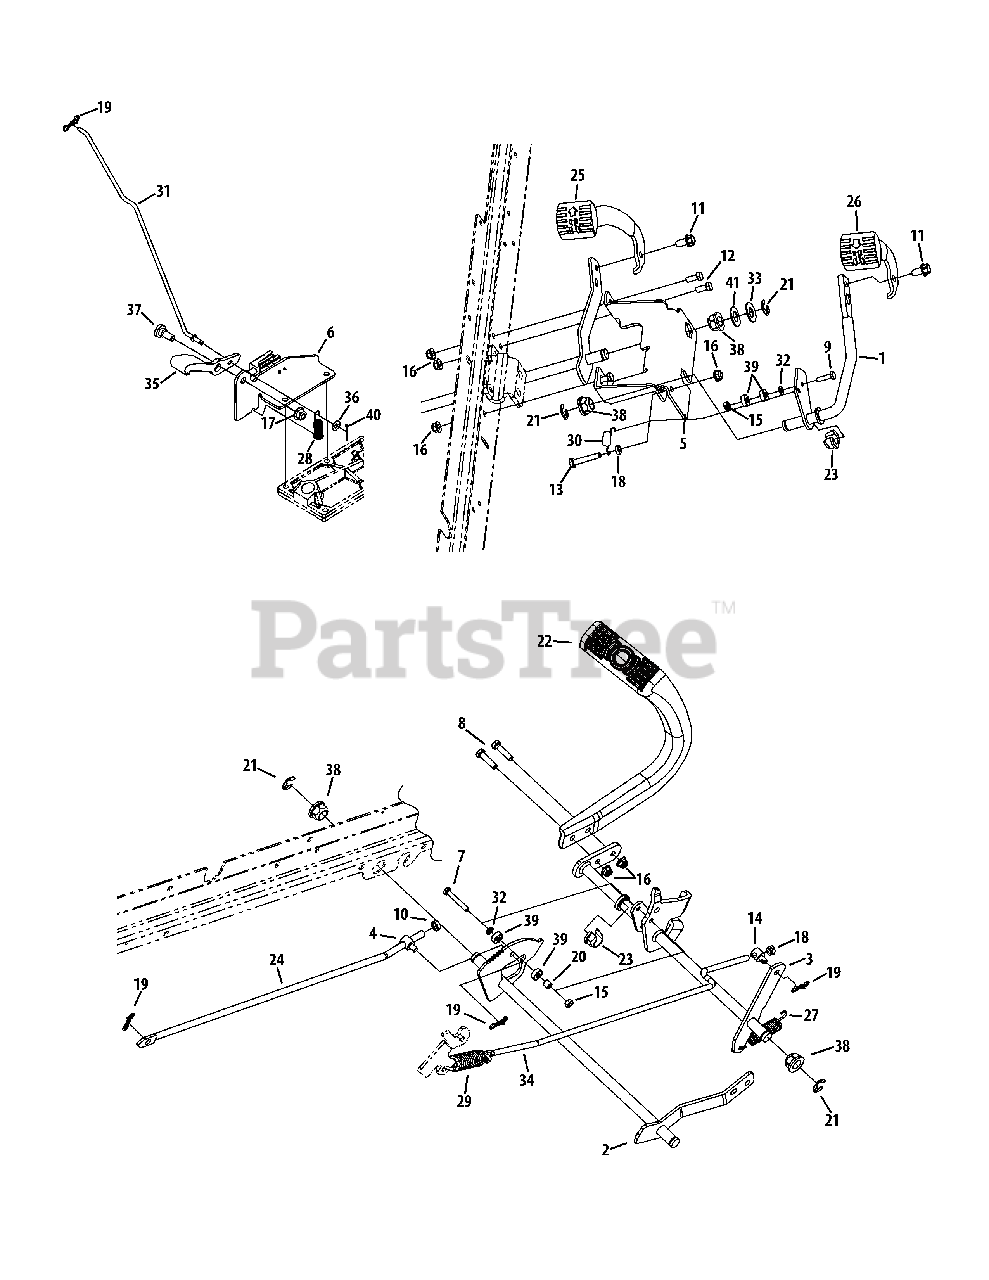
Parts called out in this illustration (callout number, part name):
1	Reverse Shaft Assembly
2	Forward Shaft Assembly
3	Brake Shaft Assembly
4	Ferrule, 3/8-16 x .312
5	Pedal Bracket
6	Cruise Pedal Mount Bracket
7	Hex Screw, 1/4-20 x 1.75
8	Hex Screw, 5/16-18 x 1.25
9	Hex Screw, 1/4-20 x 1.00
10	Jam Nut, 3/8-16
11	Hex Washer Screw, 3/8-16 x .750
12	Hex Screw, 5/16-18 x .75
13	Hex Screw, 5/16-18 x 1.75
14	Ferrule, 5/16-18 x .312
15	Hex Lock Nut, 1/4-20
16	Flange Lock Nut, 5/16-18
17	Flange Lock Nut, 3/8-16
18	Jam Nut, 5/16-18
19	Bow-Tie Cotter Pin, 72
20	Spacer, .375 x .25 x .335
21	E-Ring, .625
22	Pedal Bracket
23	Hex Flange Bearing, .628
24	Hydro Control Rod
25	Forward Pedal
26	Reverse Pedal
27	Extension Spring, .770 x 3.720
28	Cruise Extension Spring
29	Extension Spring, .95 x 4.00
30	Extension Spring, .51 x 2.12
31	Latch Control Rod
32	Flat Washer, .281 x .50 x .063
33	Flat Washer, .64 x 1.24 x .06
35	Cruise Latch
36	Flat Washer, .271 x .630 x .065
37	Shoulder Screw, 3/8-16 x .50 x .27
38	Hex Flange Bearing
39	Ball Bearing, .25 x .6875 x .25
40	Cotter Pin 3/32" Dia. x 1" Lg.
41	Washer, .625 x 1.00 x .030
